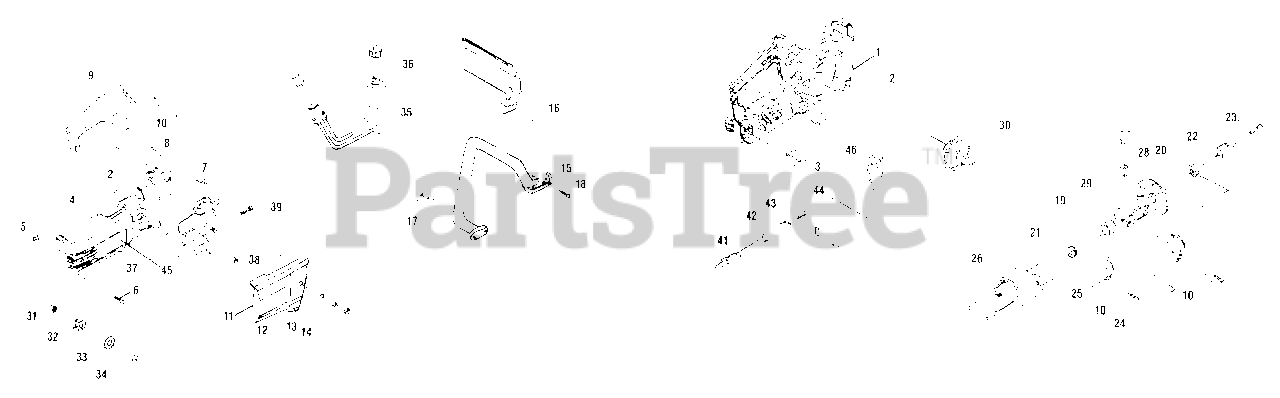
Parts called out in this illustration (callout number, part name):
1	CASE - LEFT
2	BUSHING
3	HOLDER (L)
4	CASE - RIGHT
5	HOLDER (R)
6	SCREW - TAPPING
7	PACKING
8	SCREW - 4X10 -- TAPPING
9	HANDLE - REAR
10	SCREW - TAPPING
11	BAR HOLDER ASSY
12	WASHER - 8
13	LOCKWASHER - 8
14	NUT - 8
15	HANDLE - FRONT
16	GUARD, HAND
17	SCREW -- TAPPING
18	SCREW
19	ARMATURE
20	BEARING, BALL - 6000
21	BEARING, BALL - 627ZZ
22	GEAR - PINION
23	SCREW - 4X25
24	CLAMP, FRONT
25	CLAMP - REAR
29	HOLDER, BRUSH
30	MAIN GEAR ASSY
32	SPROCKET
33	PLATE, SIDE
34	NUT
35	OILER TANK ASSY
36	CAP
37	BAR MOUNT ASSY
38	TENSIONER, CHAIN
39	SCREW, TENSIONER
41	POWER CORD
42	PROTECTOR, CORD
44	SCREW - TAPPING
45	NAME PLATE
46	SWITCH
